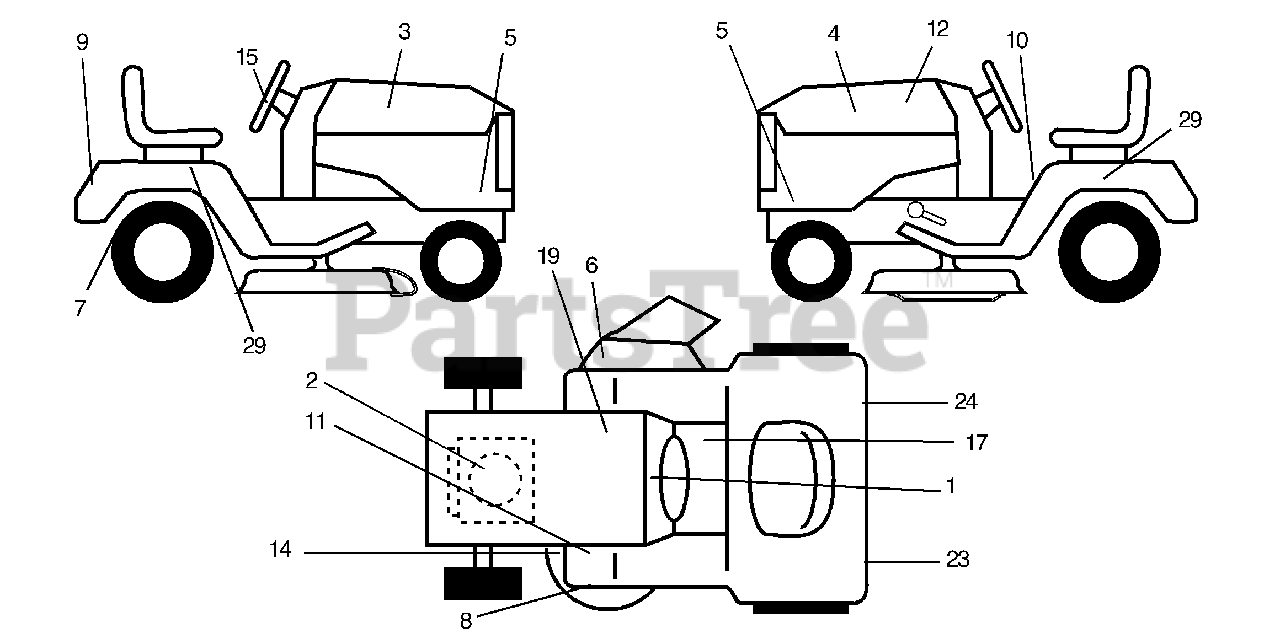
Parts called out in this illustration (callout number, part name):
1	Decal, Dash
2	Decal, Engine
3	Decal, Hood, RH
4	Decal, Hood, LH
5	Decal, Hood Sides
6	Decal, Warning
7	Decal, Bypass
8	Decal, Deck Caution
9	Decal
10	Decal, Danger
11	Ft. Rest
12	Decal, Final Replacement
14	Decal, V-Belt Schematic
15	Decal, Ins. Whl. Strg.
17	Decal, Saddle Brake Parking
19	Decal, Battery
23	Reflector, Taillight LH
24	Reflector Taillight RH
29	Decal, Fender Auto Trans
